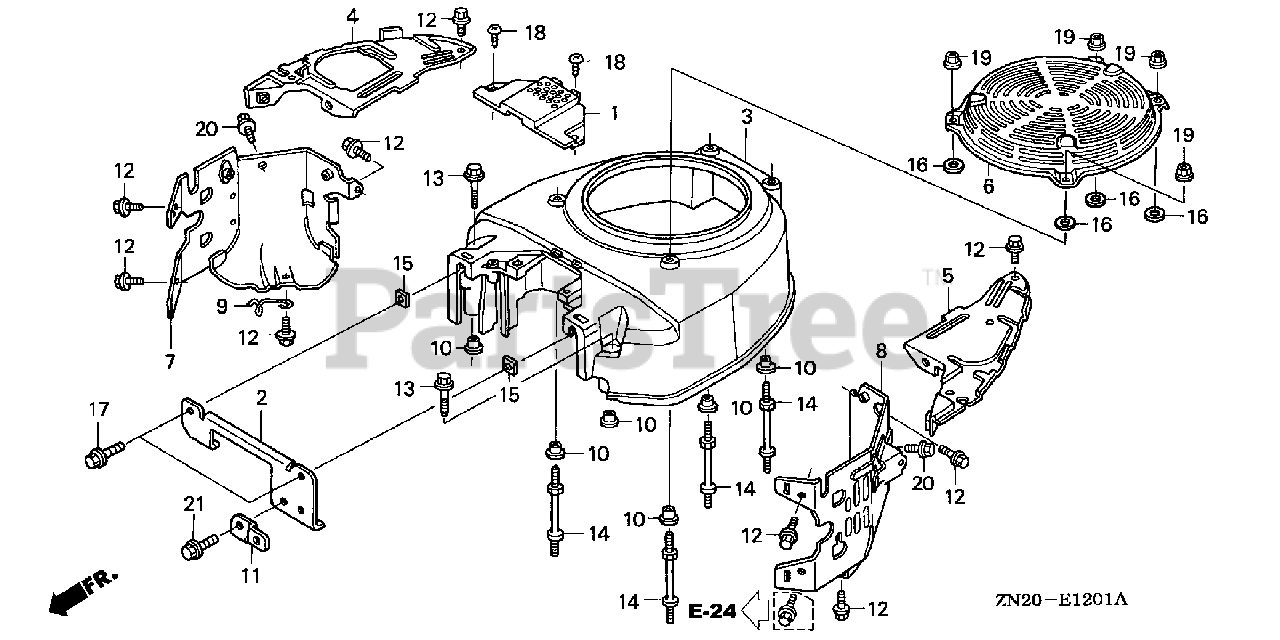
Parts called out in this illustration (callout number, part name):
1	COVER, FUEL PUMP
2	COVER, FUEL PUMP
3	COVER, FAN *R8* (RECOIL STARTER) (BRIGHT RED)
4	PLATE, R. SIDE
5	PLATE, L. SIDE
6	PROTECTOR, FAN COVER *R8* (BRIGHT RED)
7	SHROUD, R.
8	SHROUD, L.
9	CLAMP, IGNITION TUBE
10	COLLAR B, TAILLIGHT
11	BASE, CLIP
12	BOLT, FLANGE (6X12) (CT200)
13	BOLT, FLANGE (6X23)
14	BOLT, STUD (6X71)
15	NUT, SQUARE (5MM)
16	WASHER, CRANK ARM
17	SCREW-WASHER (5X12)
18	SCREW, TAPPING (5X20)
19	NUT, FLANGE (6MM)
20	BOLT, FLANGE (6X8)
21	BOLT, FLANGE (6X12)
